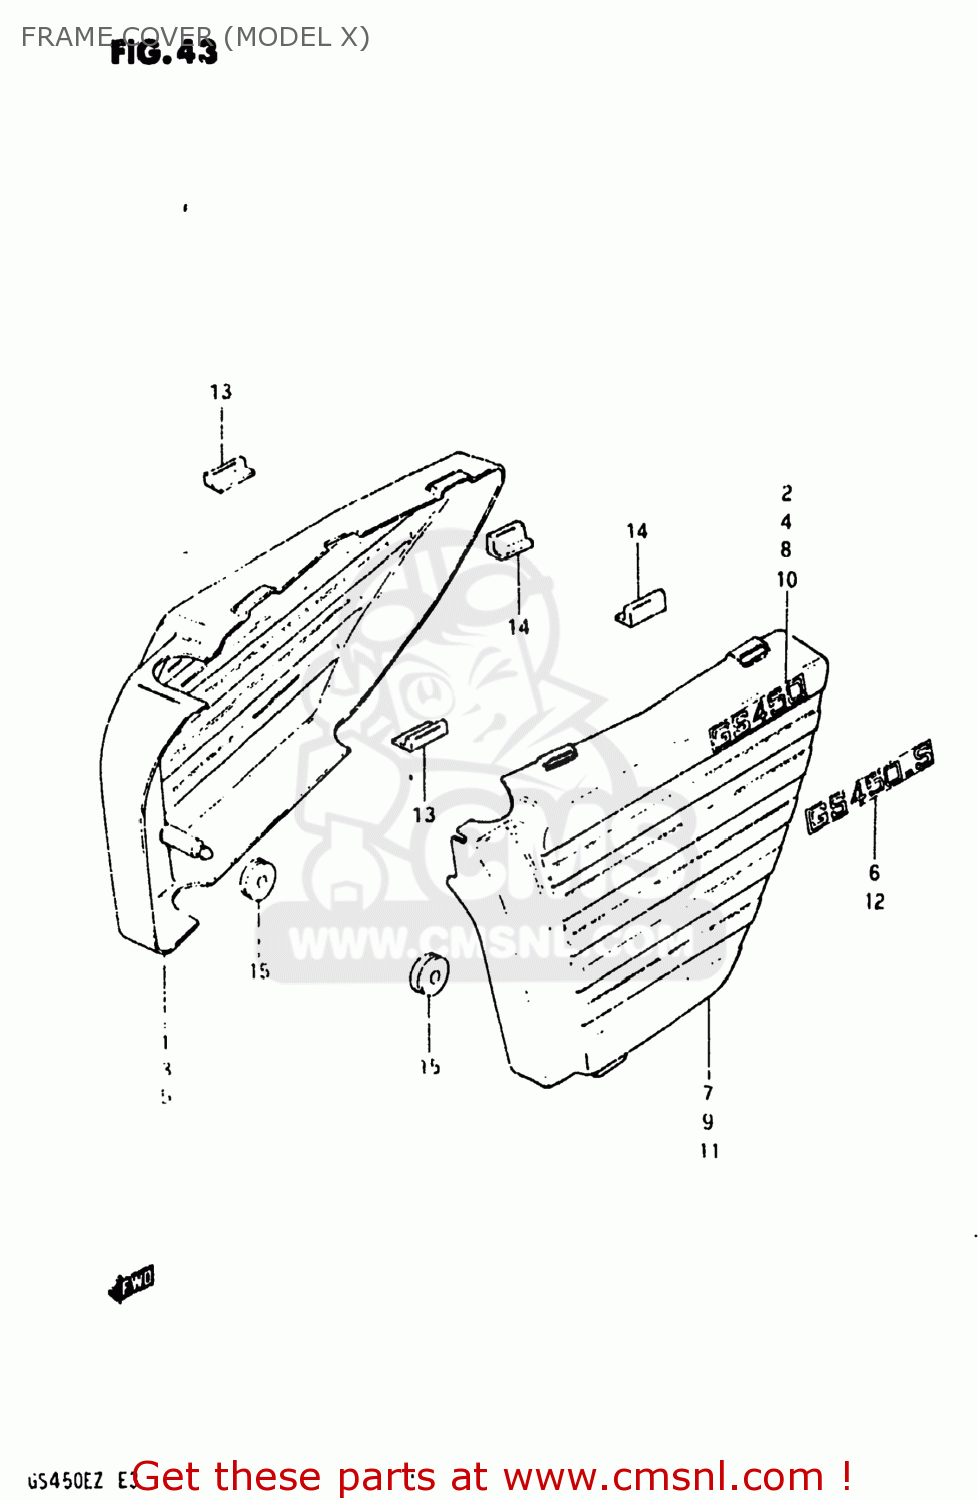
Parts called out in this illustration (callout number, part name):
1	COVER,FRAME,RIGHT
2	EMBLEM (450)
3	COVER,FRAME,RIGHT
4	EMBLEM,FRAME COVER
5	COVER,FRAME,RIGHT
6	EMBLEM
7	COVER,FRAME,LEFT
8	EMBLEM (450)
9	COVER,FRAME,LEFT
10	EMBLEM,FRAME COVER
11	COVER,FRAME,LEFT
12	EMBLEM
13	CUSHION,FRAME COVER
14	CUSHION,FRAME COVER
15	CUSHION
